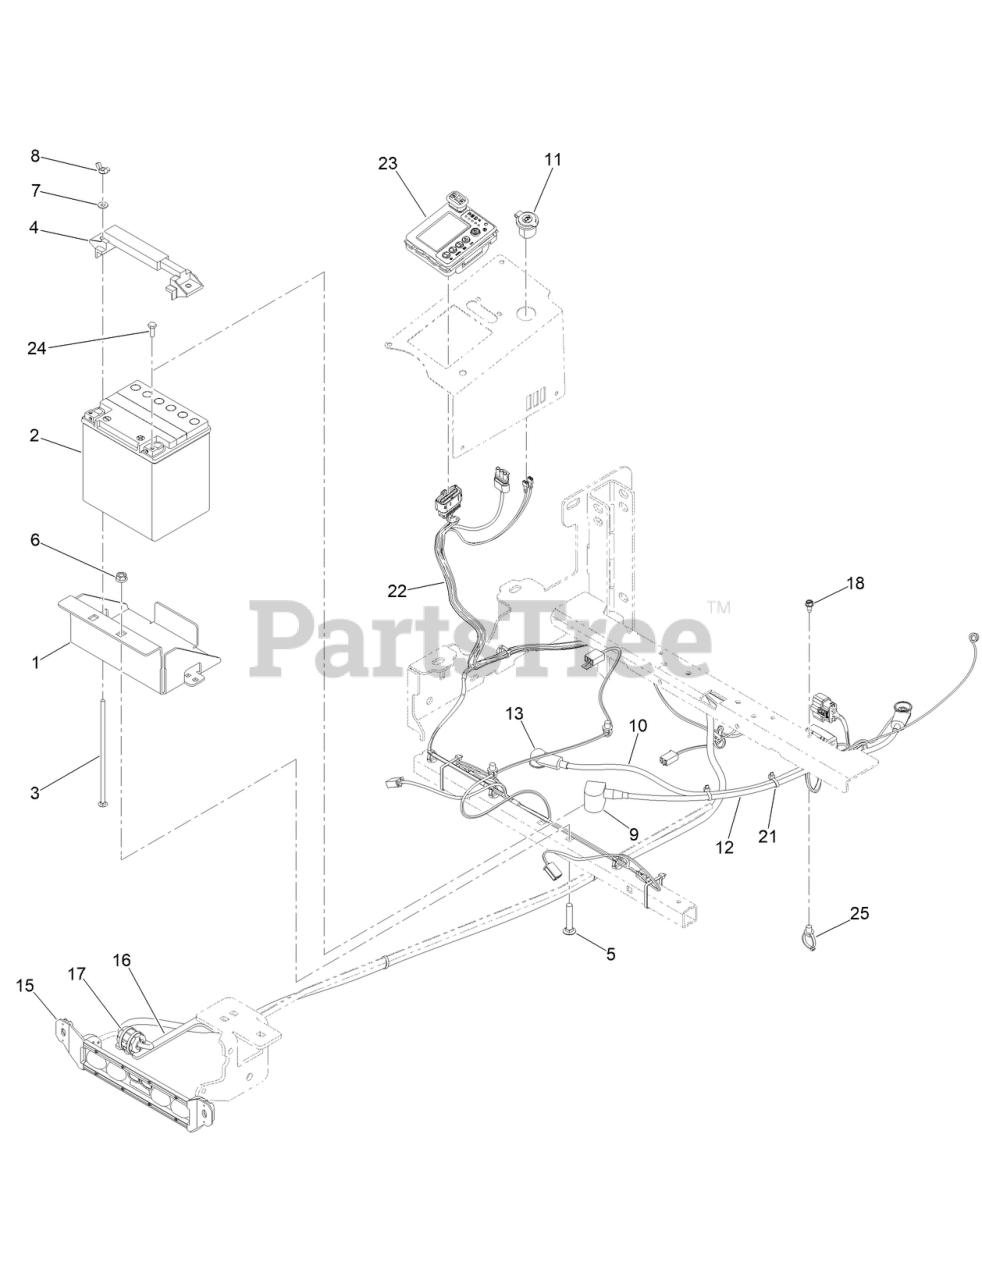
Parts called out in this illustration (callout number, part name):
1	MWR BATTERY BOX BLACK
2	BATTERY - ETX30LA - 400CCA
3	1/4IN-20X8IN GR5 CARRIAGE BOLT
4	BATTERY HOLD DOWN
5	SCREW-CARR
6	3/8-16 HEX FLANGE NUT W/SERR ZINC YELLOW
7	WASHER-FLAT
8	NUT-WING
9	INSULATOR-BATTERY
10	MWR NEGATIVE CABLE 28
11	12 VOLT AUXILLIARY PLUG
12	MWR POSITIVE BATTERY CABLE 25IN
13	STRAIGHT INSULATING TERMINAL COVER
15	FULL BEAM WITH LIGHTED HELMET LIGHT BAR
16	FAIR-RITE BRACKET PAINTED
17	FAIR-RITE ROUND CABLE SNAP-IT SIZE B
18	SCREW-HWH
21	TIE-CABLE
22	HARNESS-WIRE
23	CONSOLE-VG ADVANCE
24	SCREW-HH
25	CLIP-TIE
